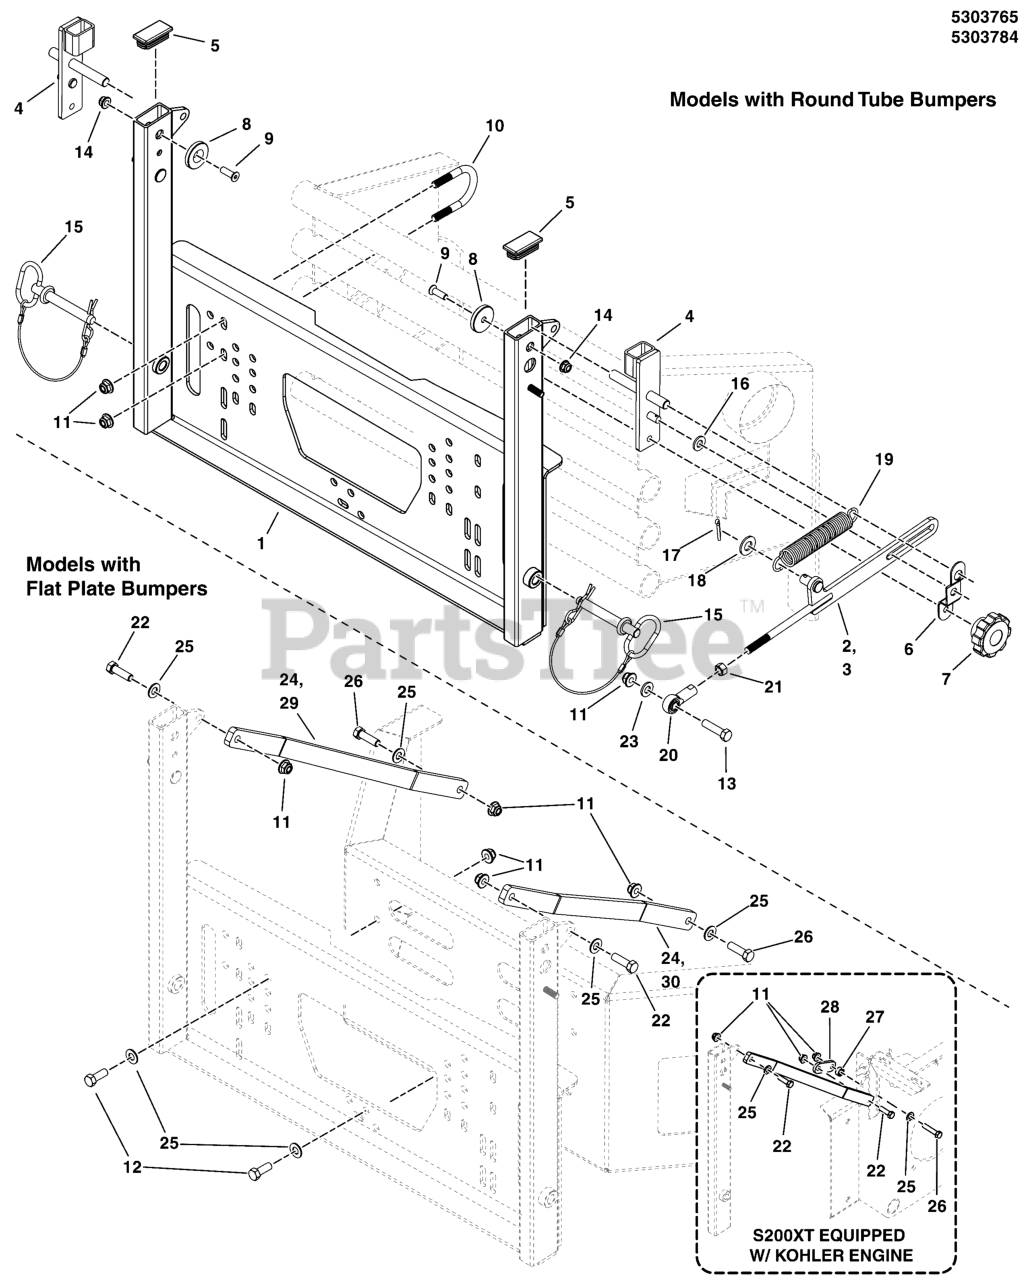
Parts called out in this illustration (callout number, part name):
1	WELD, MOUNT ASSY, 3100Z/200X-XT - BLK
2	WELD, LATCH BAR, IS3100/200XT, CZ
3	WELD, LATCH BAR, IS3100/200XT, CZ
4	WELD, PIN LOCK, HOPPER - BLK
5	PLUG, 1 X 2, 10-14 GA. TUBING
6	PLATE, PIN LOCK - BLK
7	KNOB-INT THR .312-18 4-ARM 2.12WD 1.06LG
8	SPACER, .34 X 1.54 X .25, PL
9	SCREW, 5/16-18X1, PHILLIPS HD. BZ
10	U-BOLT, 3/8 X 1-1/4
11	NUT, 3/8-16 HEX NYLOCK FLANGE
12	BOLT, 3/8-16 X 1" GD5 CZ
13	BOLT, 3/8-16 X 1-1/2" GD5 CZ
14	NUT, 5/16-18 HEX NYLOCK FLANGE
15	PIN, HITCH, .50 X 3.25 W/ LAY
16	WASHER, 3/8 X 1 X 1/16, NYLON F/W
17	PIN, 3/32 X .750, COT, ZINC/CLEAR
18	WASHER, 1/2 SAE
19	SPRING, EXTENSION, 1.00
20	BALL JOINT, 3/8-24 FEMALE
21	NUT, 3/8-24 HEX JAM
22	BOLT, 3/8-16 X 1-1/4" GD5 CZ
23	WASHER, 3/8 GD.9 FLAT
24	BAR, STAY STRAP, 150XT - BLK
25	WASHER, 3/8 SAE
26	BOLT, 3/8-16 X 1-3/4" GD5 CZ
27	SPACER, .39 X .75 X .38
28	PLATE, EXTENSION - BLK
29	BAR, LEFT STAY STRAP, 200XT - BLK
30	BAR, RIGHT STAY STRAP, 200XT - BLK
